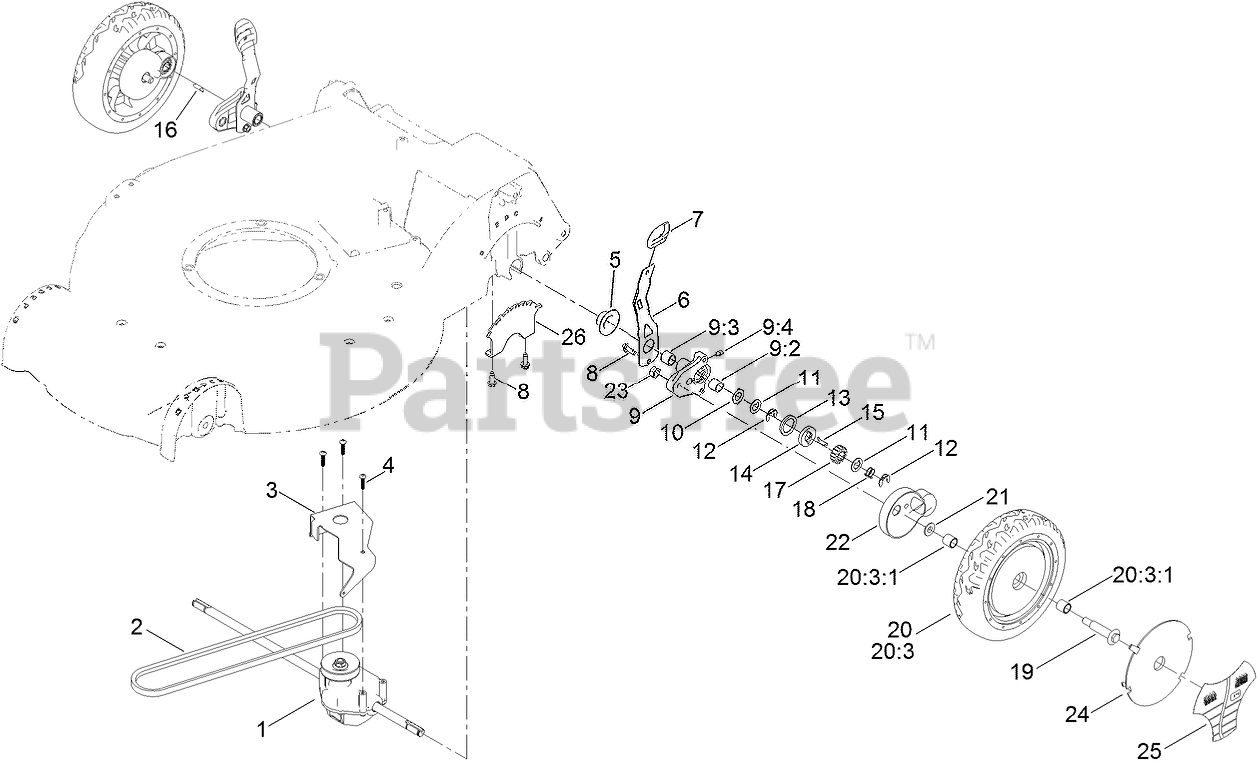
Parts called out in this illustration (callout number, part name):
1	TRANSMISSION ASM
2	BELT-V
3	BRACKET-TRANSMISSION
4	SCREW-PLASTITE
5	CAP-END
6	ARM-SPRING
7	KNOB-LEVER, HOC
8	SCREW-HWHTF
9	PIVOT ARM ASM
9:2	BUSHING
9:3	BUSHING
9:4	FITTING-GREASE
10	WASHER-ARM, PIVOT
11	WASHER-THRUST, KEYED
12	RING-RETAINING,CLIP
13	RING-FRICTION
14	WASHER-CLUTCH
15	KEY-ROCKING, L.H.
16	KEY-ROCKING, R.H.
17	GEAR-PINION
18	SPRING-COMPRESSION
19	BOLT-SHOULDER
20	8 INCH WHEEL AND GEAR ASM
20:3	8 INCH WHEEL ASM
20:3:1	BUSHING
21	SPACER-COVER, WHEEL
22	COVER-WHEEL
23	LOCKNUT
24	COVER-WHEEL
25	LABEL-WHEEL, SMART
26	PLATE-HOC
